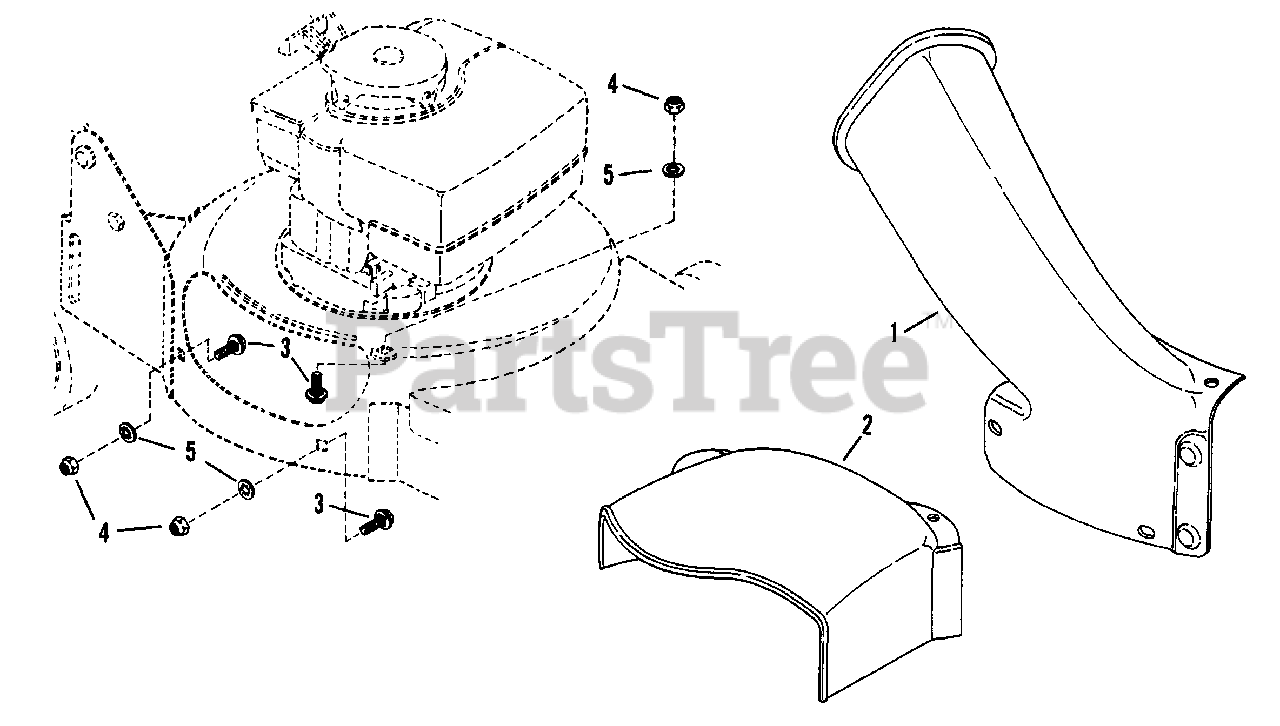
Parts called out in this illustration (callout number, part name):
1	ADAPTER, Bag
2	CHUTE, Side
3	BOLT, 5/16-18 x 5/8" Short Neck Carriage, Grade 5
4	NUT, 5/16-18 Hex Flange Center Lock
5	RETAINER, 5/16 Bolt
